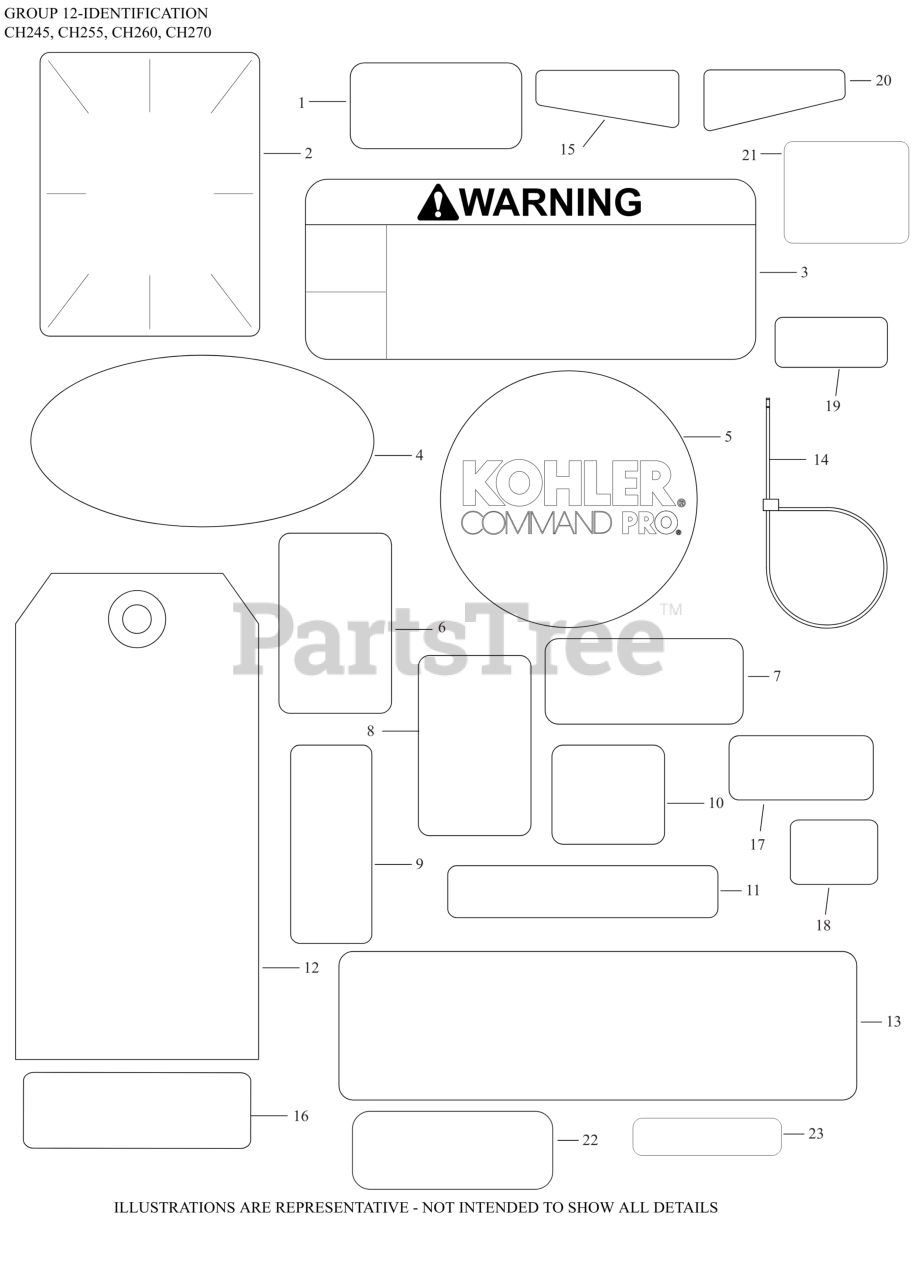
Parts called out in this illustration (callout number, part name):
1	LABEL, MAINTENANCE (CKY)
2	LABEL, CLEAR LAMINATION
3	DECAL, WARNING
4	DECAL, QUAD CLEAN SILVER
5	LABEL, RECOIL 62MM
6	DECAL, SNOW FLAKE
7	LABEL, CANADIAN COMPLIANCE
8	DECAL, SUN
9	DECAL, FUEL/CHOKE - ON/OFF
10	DECAL, BASE ARROW
11	DECAL, THROTTLE
16	DECAL, ENGINE AND FUEL SHUT OFF
17	DECAL, ETHANOL WARNING
